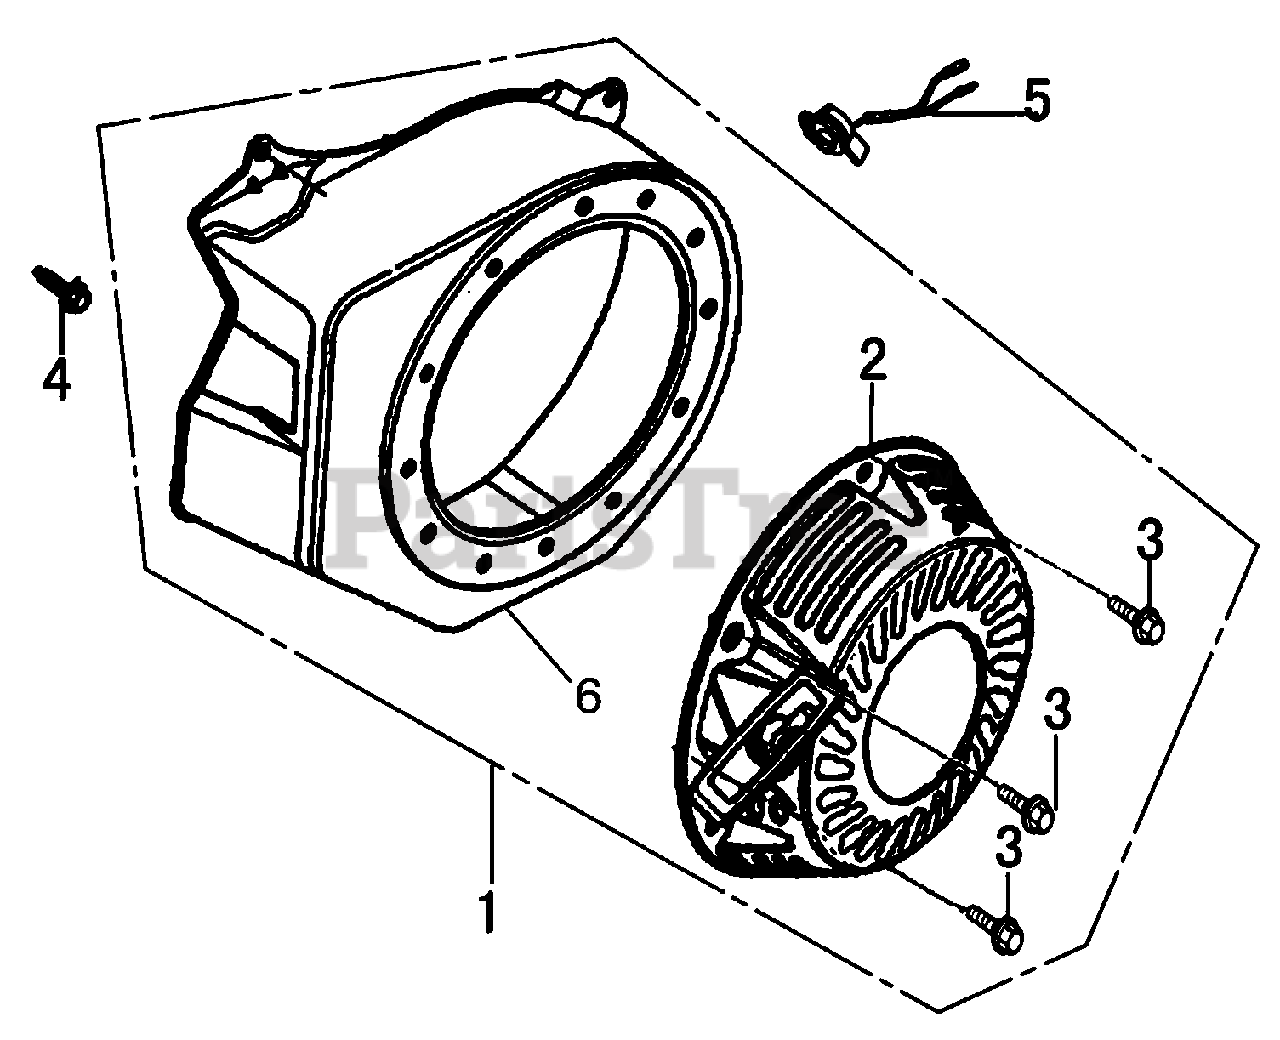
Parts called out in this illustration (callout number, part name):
1	RECOIL STARTER w/ BLOWER HSNG.
2	STARTER ASSY., RECOIL
3	BOLT,FLANGE 6×8
4	BOLT,FLANGE 6×10
5	SWITCH ASSY., ENGINE STOP
6	BLOWER HOUSING/SHROUD
